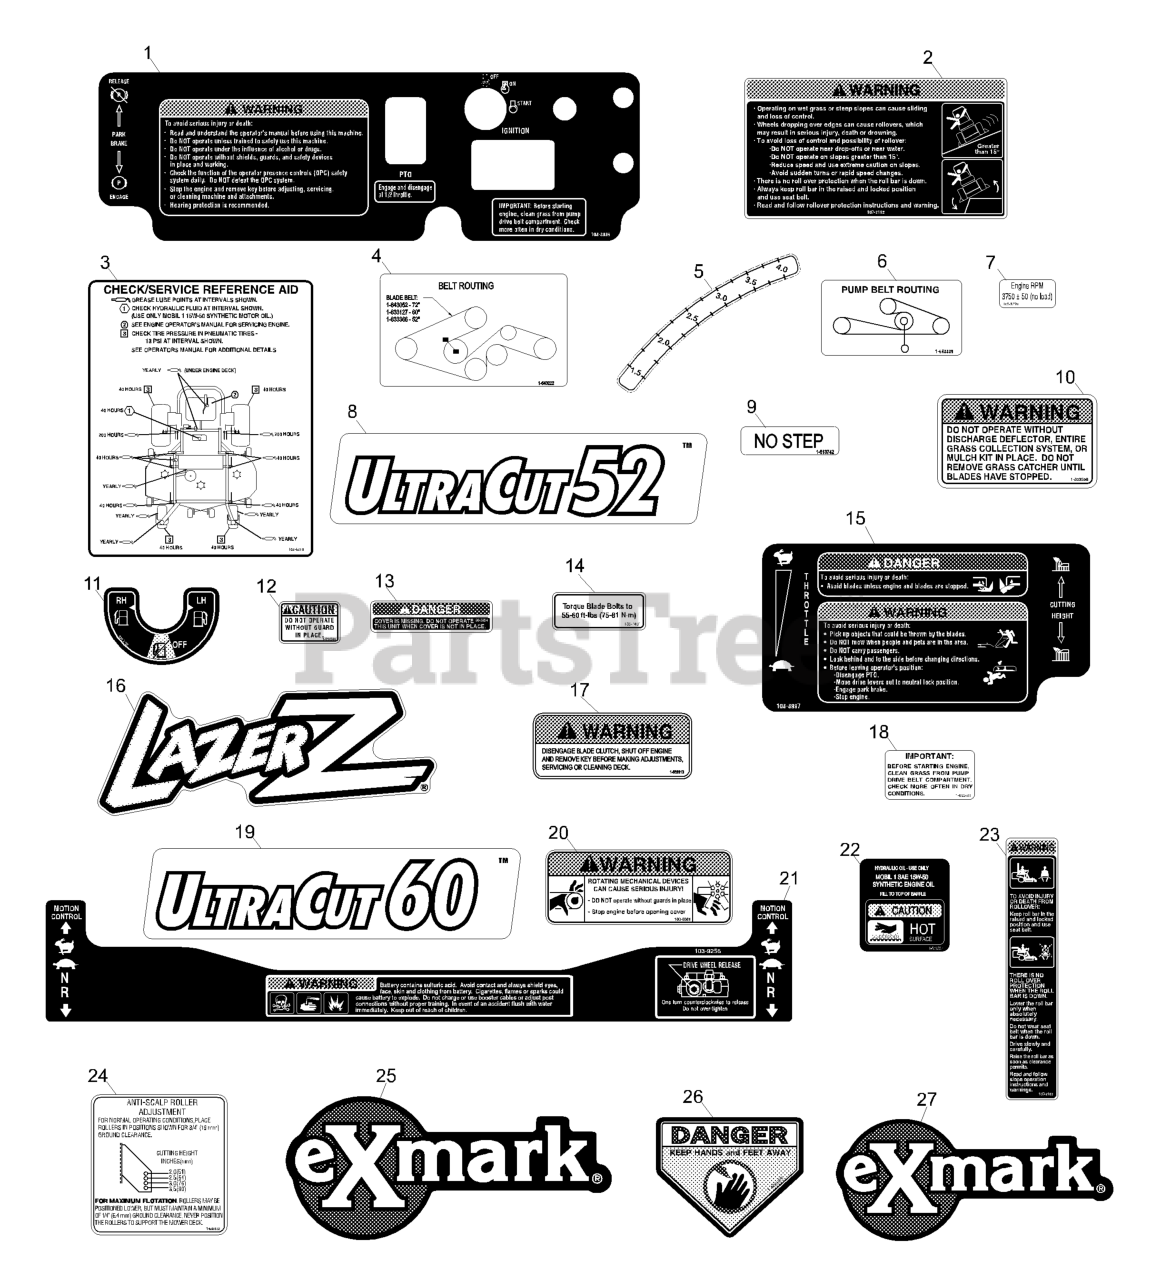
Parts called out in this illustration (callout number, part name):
1	DECAL,CONSOLE
2	DECAL-WARNING
3	DECAL,CHECK SERVICE LZ
4	DECAL,BELT ROUTING
6	DECAL-ROUTING, BELT
8	DECAL,ULTRACUT 52
9	DECAL,NO STEP
10	DECAL-WARNING, DISCHARGE
11	DECAL-VALVE, FUEL
12	DECAL-GUARD
13	DECAL-COVER, MISSING
16	DECAL,LAZER MODEL
17	DECAL,WARNING
18	DECAL-IMPORTANT
19	DECAL,ULTRACUT 60
20	DECAL-DEVICES, ROTATING
23	DECAL-WARNING, FOLDING RO
24	DECAL,ANTISCALP
25	DECAL,EXMARK LOGO
26	DECAL-DANGER
27	DECAL,EXMARK LOGO
